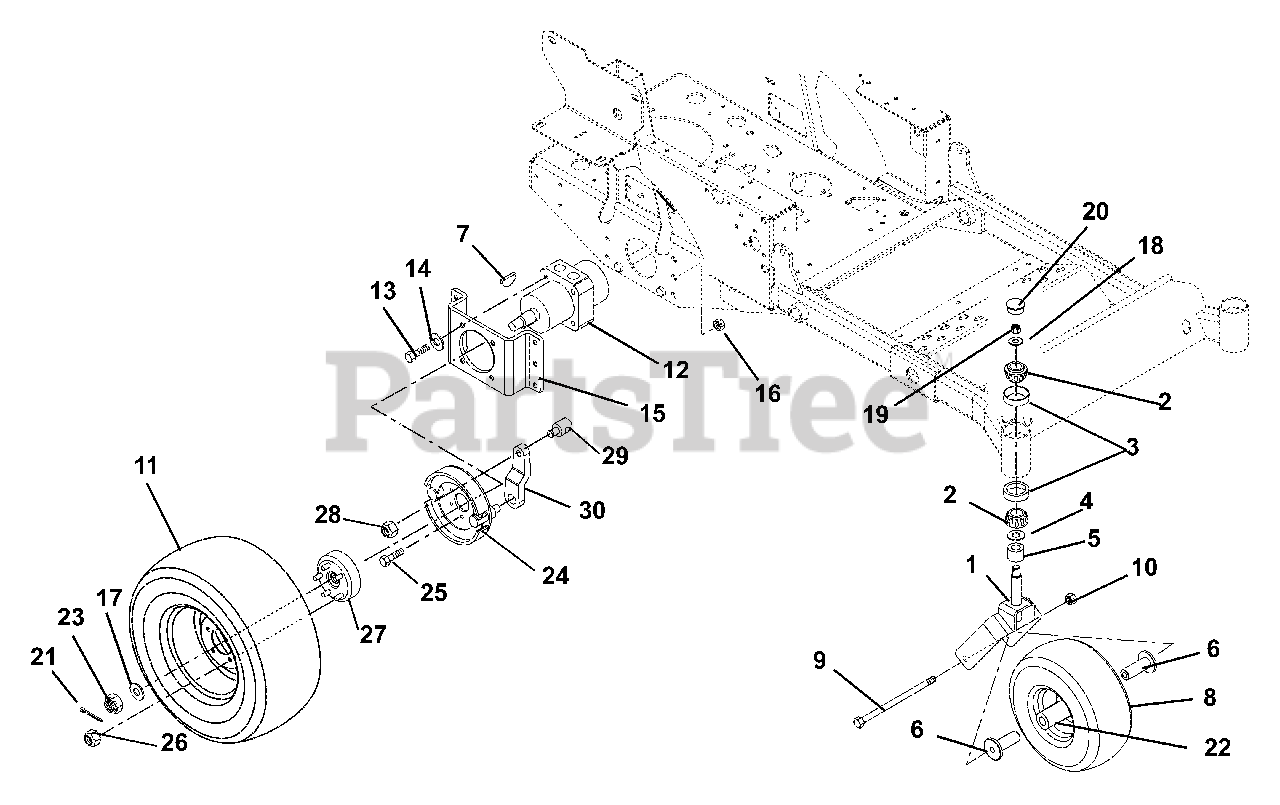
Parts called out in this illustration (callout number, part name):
1	WMT, FRONT FORK
2	BRG-CONE 1.0X.58
3	BRG-CUP1.980X.420
4	BEARING SEAL 1.5 X 2 X .18
5	SPACER 1.005X1.5075X.375
6	SPACER, WHEEL
7	KEY-WDRF .19X.75 HRD #9
8	ASSM TIRE\WHEEL 5.25 X 13.00
9	@BLT-HEX .50-13X7.50 GR5 YWZC
10	@NUT-LK-NYL-FLG .50-13 YWZC
11	TIRE/WHL 20X10-10 4PR
12	MOTOR, HYD WHEEL
13	@BLT-HEX .38-16X1.00 GR5 YWZC
14	@WSHR-LK .38X.094 REG YWZC
15	BRKT, WHEEL MOTOR
16	@NUT-LK-NYL-FLG .38-16 YWZC
17	WSHR-FL-STL.755X1.375X.062YWZC
18	@WSHR-FL-STL.812X1.50X.135YWZC
19	NUT-JAM CTRLK .75-16 YWZC
20	CAP, DUST
21	@PIN-CTR EXTPRSQCT .09X1.25 YZ
22	BRG, 25MM ID X 52MM OD X 15MM
23	NUT-HEX-SL .75-20
24	BRAKE, MECHANISM W/ PADS
25	SCR-SKH M6X16 SHCS GR5 EP30
26	NUT-LUG .50-20 YWZC
27	HUB, 5-BOLT BRAKE DRUM
28	@NUT-LK-CTR-JAM .31-18 YWZC
29	PIN, PIVOT/TRUNNION
30	ARM, BRAKE HYDRO-GEAR
